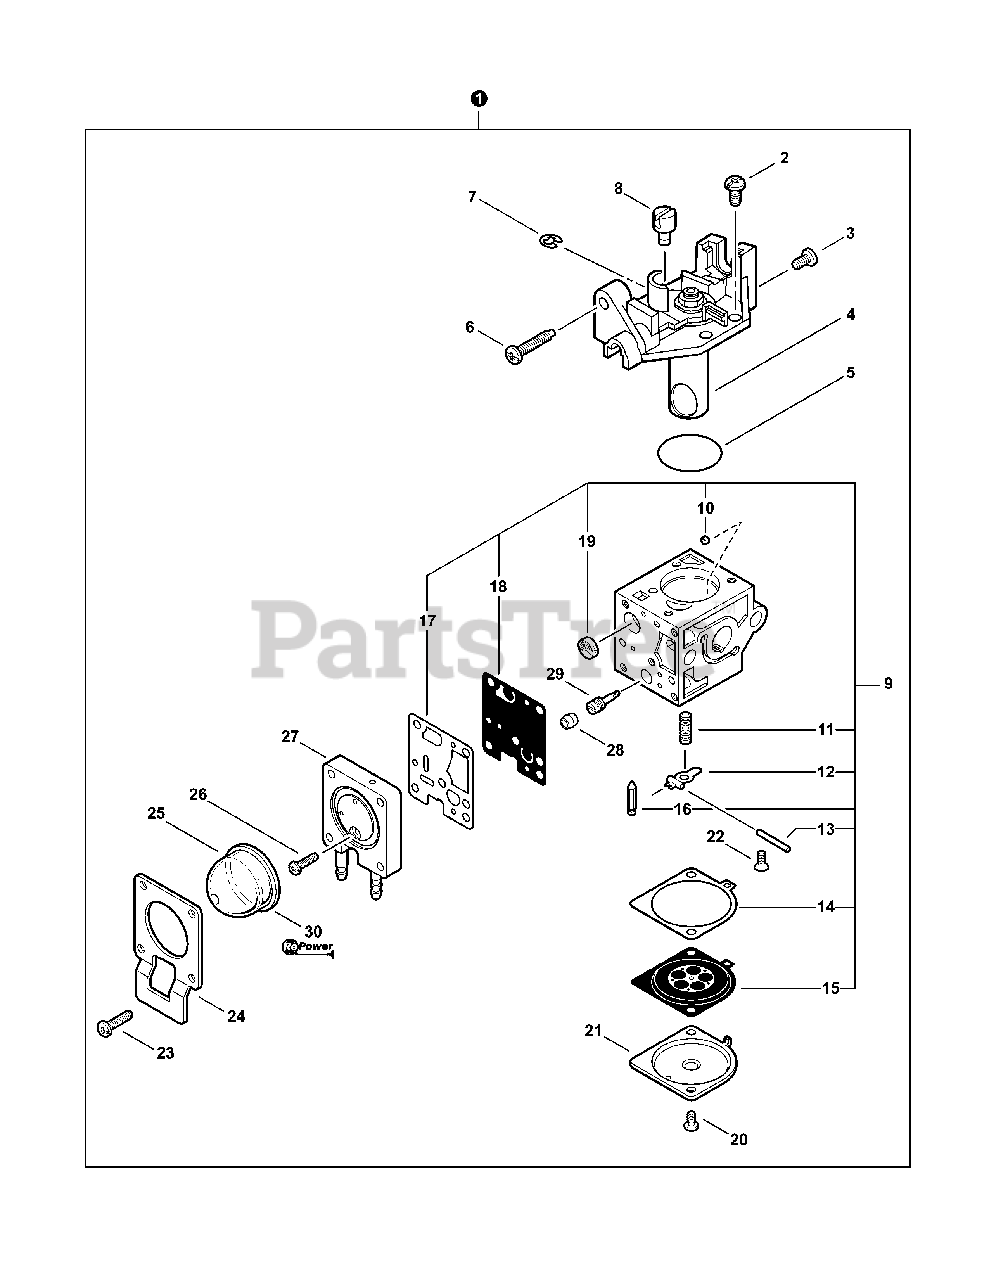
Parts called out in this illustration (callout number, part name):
1	CARBURETOR -- RB-K93
4	ROTOR COVER ASSY
6	SCREW, IDLE ADJUST
7	RING, RETAINING
9	REPAIR KIT
10	GUIDE, ROLLER
11	SPRING, METERING LEVER
12	LEVER, METERING
13	PIN, METERING LEVER
14	GASKET, DIAPHRAGM
15	DIAPHRAGM, METERING
16	VALVE, INLET NEEDLE
17	GASKET, PUMP
18	DIAPHRAGM, PUMP
19	STRAINER
21	COVER, METERING
22	SCREW, METERING LEVER PIN
23	SCREW, PURGE BULB RETAINER
24	RETAINER, PURGE BULB
25	BULB, PURGE
26	SCREW, PURGE BASE
27	BASE, PURGE
29	NEEDLE - HIGH SPEED
30	RePower FUEL SYSTEM KIT
